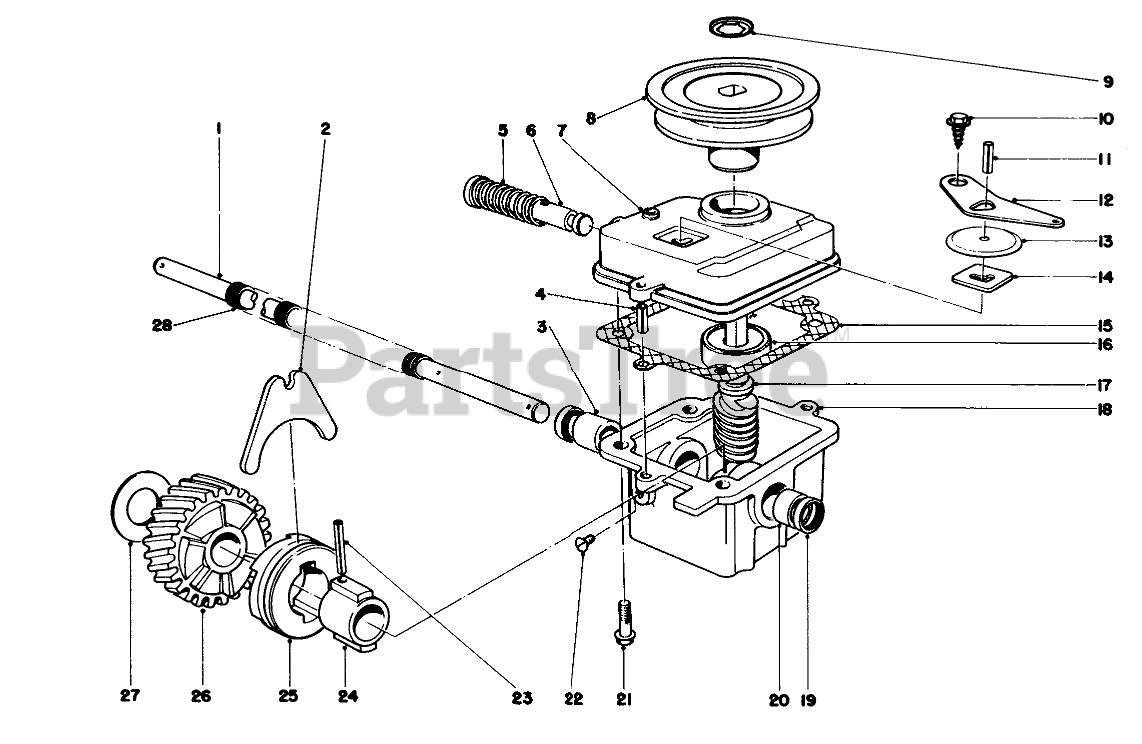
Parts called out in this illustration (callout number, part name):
1	Drive Shaft
2	SHIFTER FORK
3	Bushing
4	3/16 X 1/2 ROLL PIN
5	SPRING
6	Shift Rod
7	GEAR CASE COVER
8	PULLEY
9	PUSH-ON 93-3236
10	Screw
11	PIN-ROLL
12	SHIFTER ARM
13	TRANS DUST COVER
14	LATCH PLATE
15	GASKET
16	Bearing
17	WORM SHAFT
18	Gear Case (Incl. Ref. #3, 19-20)
19	Seal
20	Bushing
21	Screw
22	NYLON SCREW
23	COIL PIN
24	SLEEVE
25	CLUTCH JAW
27	THRUST WASHER
28	DRIVE SHAFT COVER
